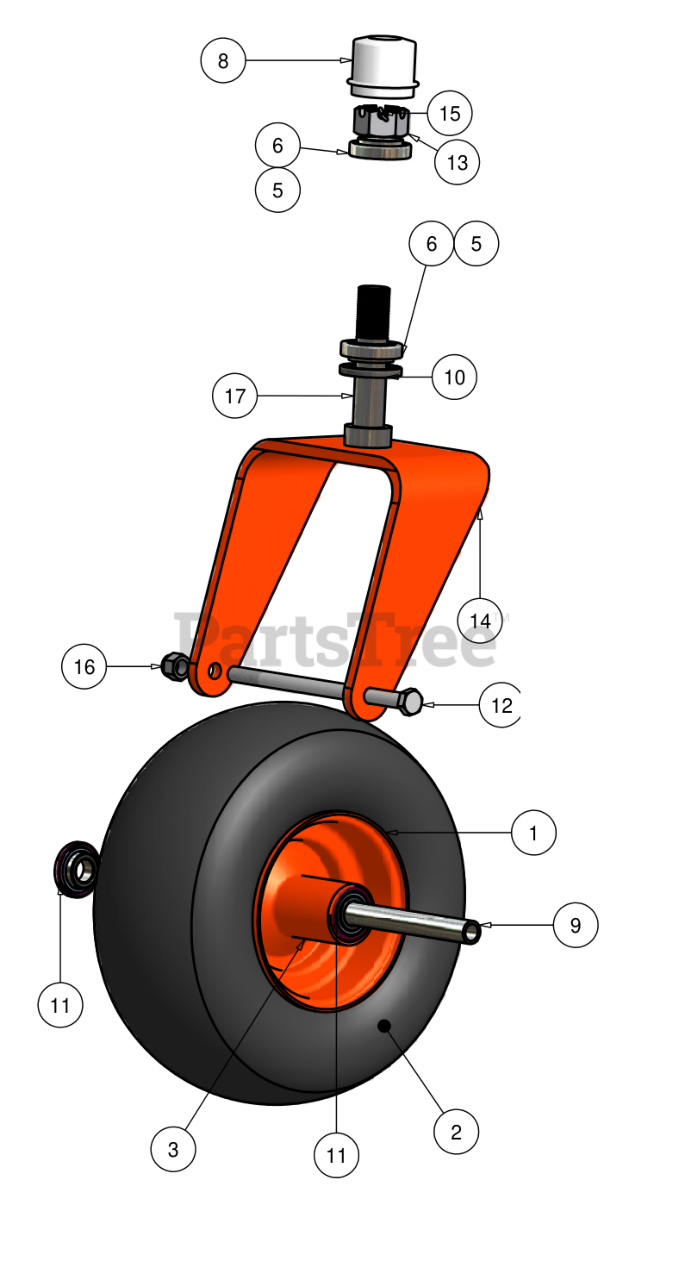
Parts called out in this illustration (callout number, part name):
1	13" x 6.50 - 6" Tire
2	13" x 6.50-6" Tire
3	6" Wheel ONLY
8	Dust Cover
9	Front Wheel Spacer
11	Wheel Bearing
12	1/2" x 9" Bolt
13	1" Fine Threaded Castle Nut
14	Front Fork with Spindle
15	1/8" x 2 1/4" Cotter #8
16	1/2" Nylock Nut
17	Front Fork Spindle
